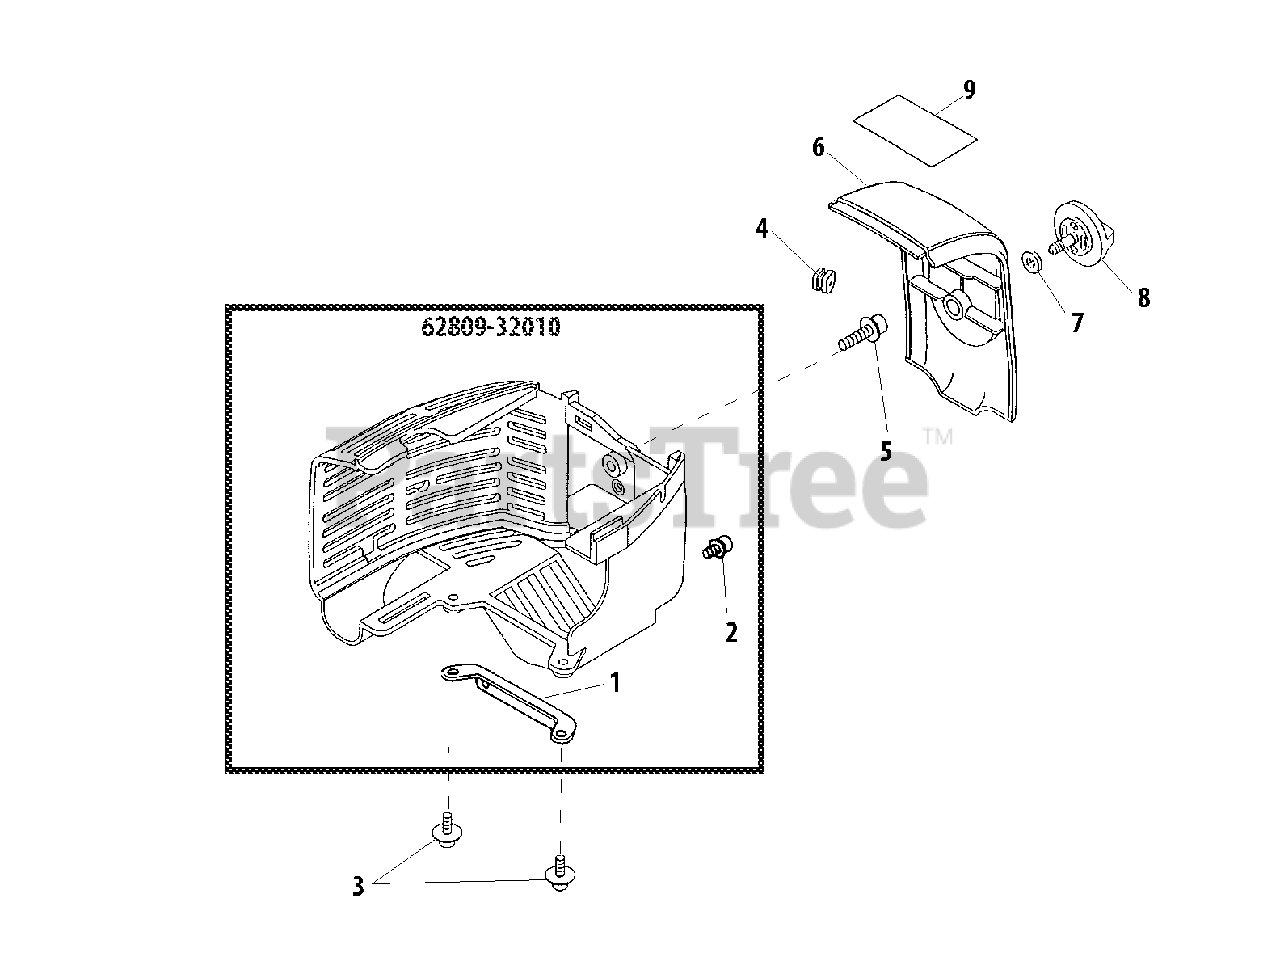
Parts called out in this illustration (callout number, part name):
1	BRACKET
2	BOLT
3	BOLT
4	GROMMET, LEAD
5	BOLT, ADHESIVE M5×20
6	COVER
7	WASHER 5
8	THUMBSCREW
9	LABEL
62809-32010	ENGINE COVER KIT
